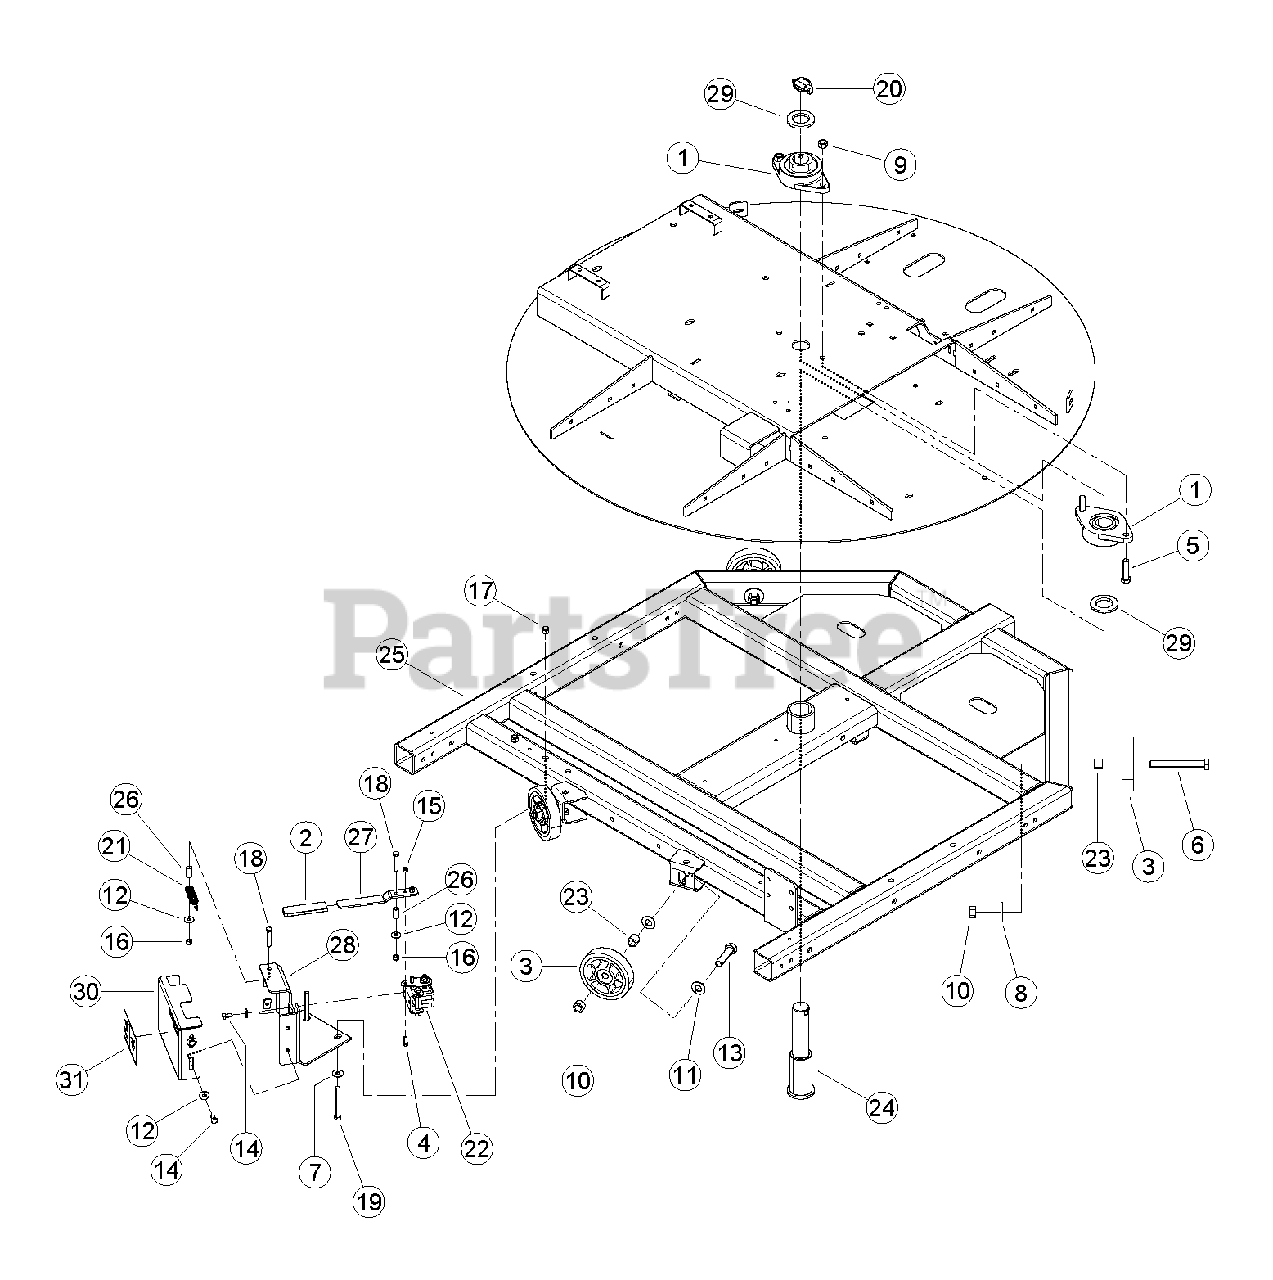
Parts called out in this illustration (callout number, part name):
1	BEARING, 1-1/2 2-BOLT SET SCREW
2	GRIP, CLUTCH HANDLE
3	ROLLER, 5 X 1 X 5/8 NOFF AL
4	BOLT, 1/4 X 3/4 HEX HD GR5 ZP
5	BOLT, 1/2 X 2 HEX HD GR5 ZP
6	BOLT, 5/8 X 5 HEX HD GR5 ZP
7	WASHER, 3/8 FLAT ZP
8	WASHER, 5/8 FLAT ZP
9	NUT, 1/2 CENTERLOCK GRB ZP
10	NUT, 5/8 CENTERLOCK GR5 ZP
11	WASHER, 5/8 SAE FLAT ZP
12	WASHER, 5/16 FLAT ZP
13	BOLT, 5/8 X 2-1/2 HEX HD GR5 ZP
14	BOLT, 5/16 X 5/8 HEX HD GR5 ZP
15	NUT, 1/4 NE NYLOCK ZP
16	NUT, 5/16 NE NYLOCK ZP
17	NUT, 3/8 NE NYLOCK ZP
18	BOLT, 5/16-18 X 1-3/4 HCS GR5 ZP
19	BOLT, 3/8 X 3-1/4 HEX HD GR5 ZP
20	PIN, 7/16 X 1-3/4 LYNCH
21	SPRING, 3/4 OD EXTENSION
22	CALIPER, 210M BRAKE
23	SPACER, 7/8 X 3/4
24	PIN, CHIPPER PIVOT
25	WELDMENT, CHIPPER TRAILER
26	TUBE, 1/2 OD X 1.00
27	HANDLE, BRAKE
28	WELDMENT, BRAKE MOUNT
29	SPACER, 2.00 X 1.50 X 0.25
30	ASSEMBLY, BRAKE COVER SERVICE PART
31	DECAL, BRAKE
